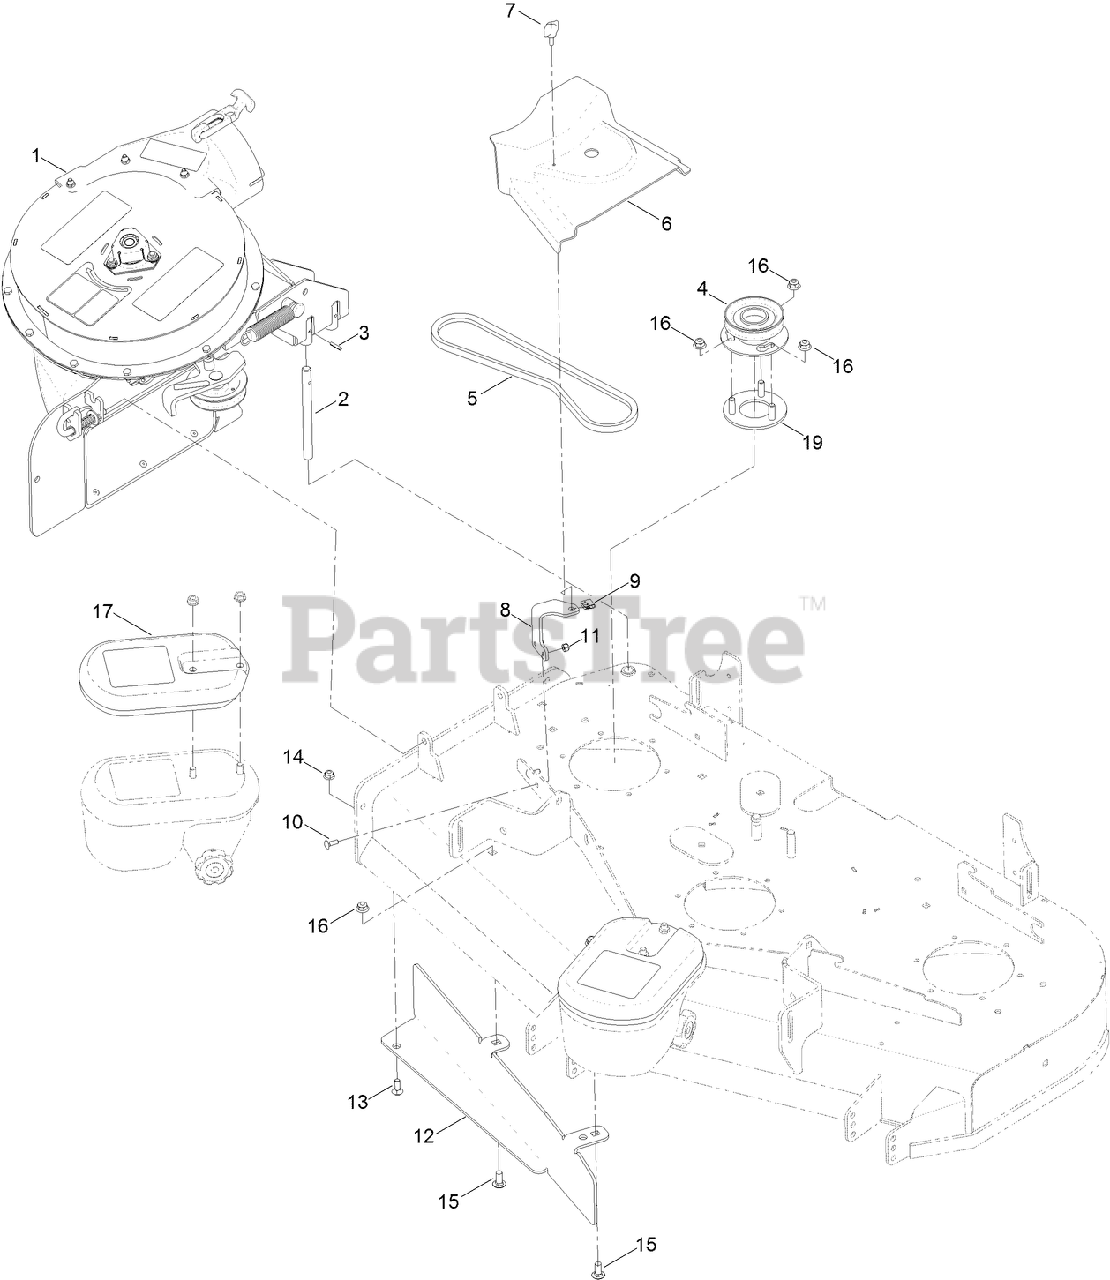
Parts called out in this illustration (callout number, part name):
1	BLOWER ASM
2	SHAFT-CATCHER, GRASS
3	PIN-ROLL
4	PULLEY-BLOWER
5	BELT-V
6	COVER-BELT
8	BRACKET-COVER, BELT
9	NUT-SPEED
10	BOLT-CARR
11	NUT-LOCK, NI
12	BAFFLE-BAGGER, 48 INCH
13	SCREW-CARR
14	NUT-HF, NI
15	SCREW-CARR
16	NUT-HF, NI
17	WEIGHT
19	MOUNT-PULLEY
